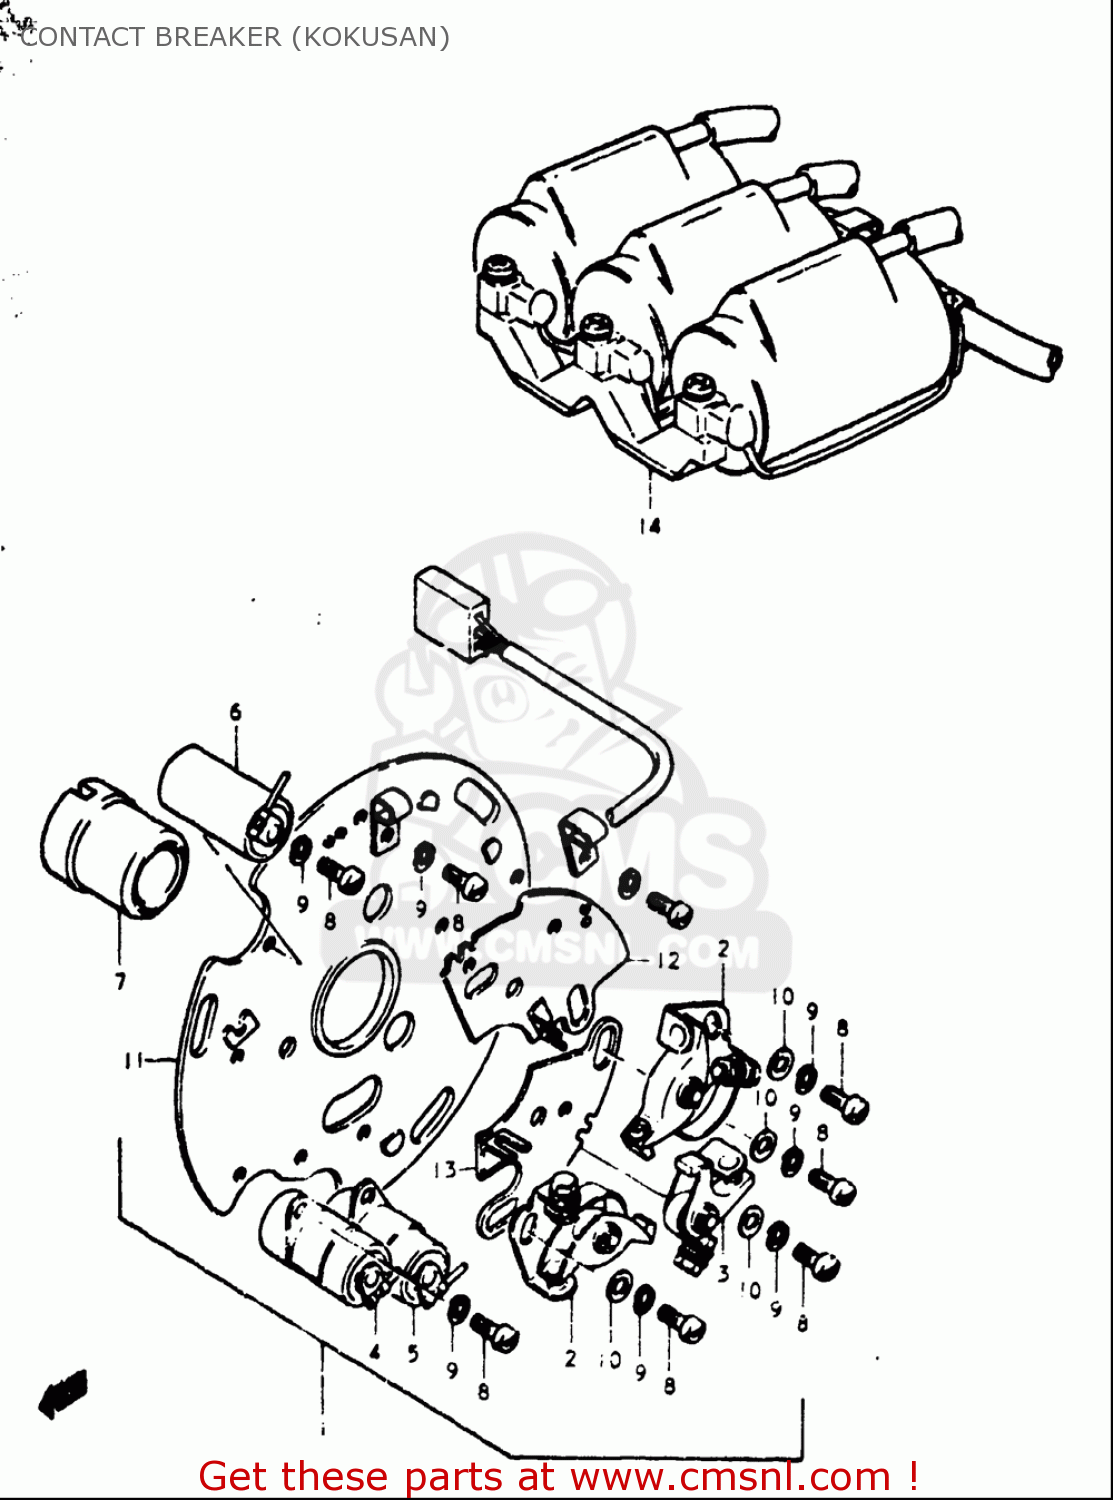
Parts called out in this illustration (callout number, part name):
2	POINT ASSY,R/L
3	POINT ASSEMBLY,CONTACT,MIDDLE
5	CONDENSER, CENTER
8	SCREW 4X6
9	WASHER,LOCK
10	WASHER
